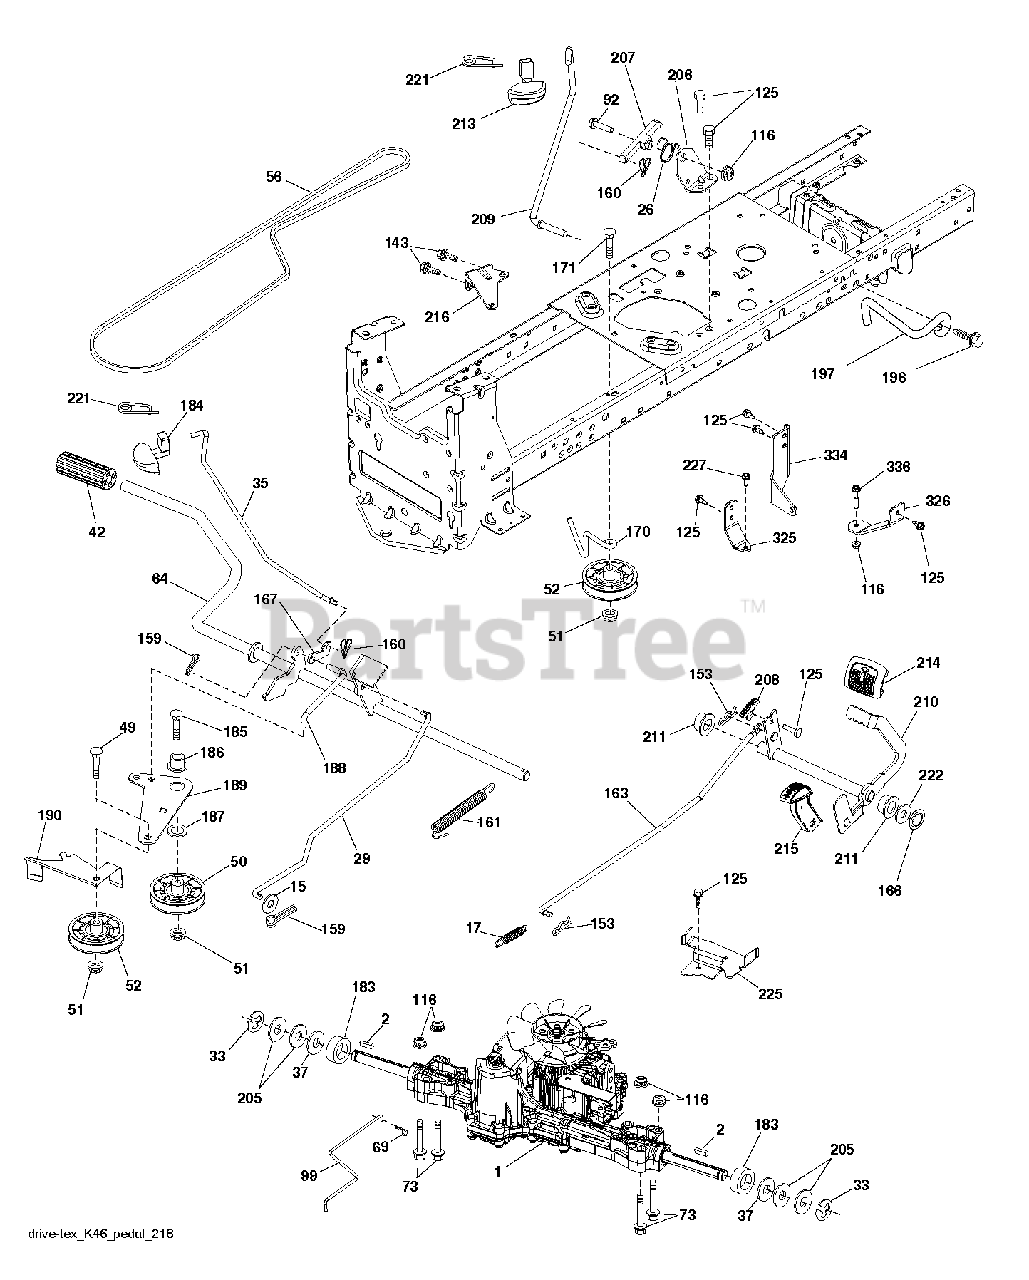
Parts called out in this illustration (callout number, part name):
2	SQUARE KEY
15	WASHER
17	SPRING.BRAKE.K46.GREEN
26	SPRING.RETURN.CRUISE
29	ROD.BRAKE.K46
35	ROD ROD.PARKINGBRAKE.GT.HUSQ/P
37	WASHER.HARDENED
42	PEDAL COVER T
50	IDLER.FLAT.910.OFFSET
51	NUT LOCK FLG 3/8-16 UNC
52	IDLER.V-GROOVE.910.OFFSET
56	V-BELT.MOWER.92.40.42/K46
64	SHAFT.ASM.PEDAL.BRK.CNTR
69	HAIRPIN.SOFT.ZINC.059X1.125
92	BOLT
99	ARM.PIVOTING.TCRD.GEN2.5.BAGGE
116	NUT LOCK HEX FLANGE 5/16-18
125	SCREW
143	SCR 5/16-18 X 1/2 SELFTAP ZN
153	RETAINER M
159	COTTER PIN
160	RETAINER CLIP
161	SPRING, RETURN LT
163	ROD.CONTROL.K57R.K46
166	NUT.PUSH.625
167	LATCH.BRAKE.SPRING
170	KEEPER.V-IDLER.CENTER.
183	SPACER AXLE
184	HANDLE.PARKING.BRAKE.H (BLK)
186	SPACER.RETAINER
187	WASHER 12/32X2X10GA
188	LINK.CLUTCH.GROUND DRIVE.LONG
189	BELLCRANK.GROUND.DRIVE.TEX.
190	KEEPER.BELLCRANK.DRIVE
196	SCREW 3/8-16X1
197	CLUTCH.ANTIROTATION.WIREFORM.
206	BRACKET.MOUNT.CRUISE.LATCH
207	LATCH.CONTROL.CRUISE.TEX
208	GEAR.SECTOR.CONTROL.CR
209	ROD ROD.CRUISECONTROL.GT.HUSQ/
210	ROCKER.ASM.PEDAL.CONTR
211	BEARING.NYLON
213	KNOB.CONTROL.CRUSIE.HU
214	PEDAL.FORWARD.PAD.TEX
215	PEDAL.COVER.REVERSE.CRD.X428BK
216	BRACKET.PULLEY.IDLER.W/TEX
221	RETAINER.SPRING.CLIP.H
222	WASHER 21/32 X 1-1/4 X 10 GA.
225	KEEPER.BELT.TRANSAXLE.K46
227	SCREW
325	BRACKET.TRQ.STP.46.20".TIRE.LH
326	BRCKT.PNT.TRQ.STP.46.20TIRE.RH
334	SWAY.ROD.BRACKET.K46
336	BOLT.5/16-18X1-3/4.FLANGED.HEX
